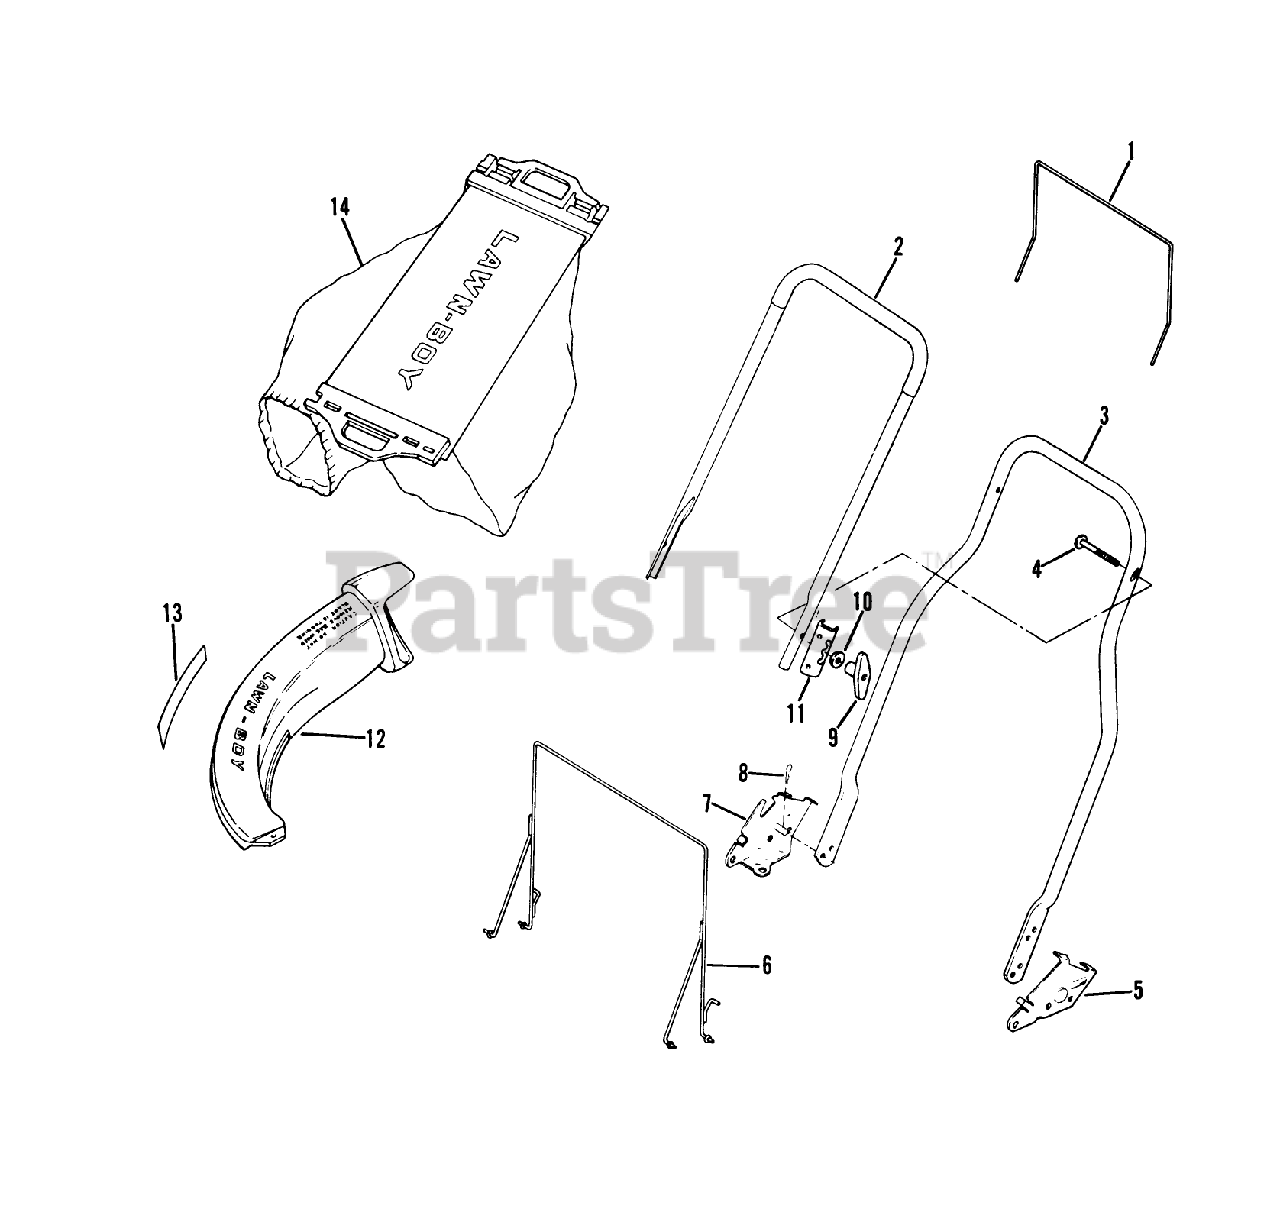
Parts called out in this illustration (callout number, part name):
1	HANGER
8	HAIR PIN
9	NUT-WING
10	WASHER-CURVED
11	BRACKET R/B 613462
